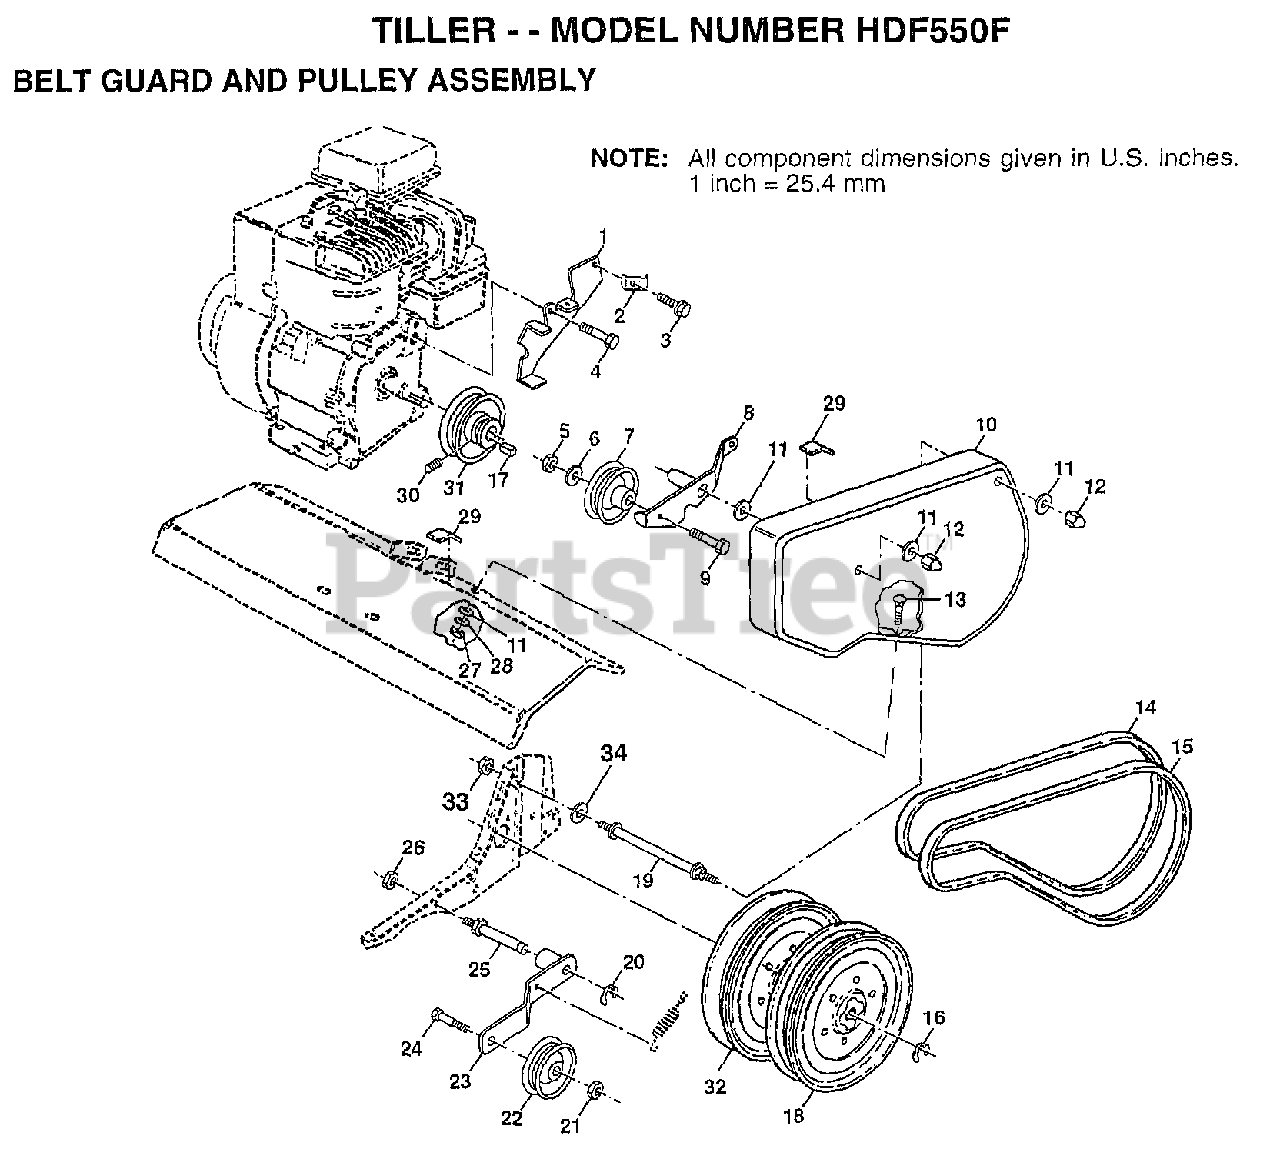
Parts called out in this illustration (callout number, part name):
1	ASM.BRKT.BELT.GRD
2	CONDIUT CLIP T
4	BOLT.HEX.HEAD
5	NUT.HEX.3/8-16UNC
6	WASHER
7	PULLEY W/SPACER
8	ARM.ASM.REV.IDLER
10	GUARD.PNT.BELT.MS-428
11	WASHER
12	NUT-CAP TI
13	BOLT T
14	BELT-V
17	KEY T
18	"SHEAVE,TRANS.""D"""
19	BOLT TI
20	KLIP RING TI
21	NUT
22	"PULLEY,IDLER"
23	"ARM, IDLER"
25	SHAFT IDLER TI
26	JAM NUT TI
28	LOCKWASHER
29	PAD IDLER TI
30	SET SCREW
31	ENGINE PULLEY TI
32	SHEAVE.TRANS
33	NUT
34	WASHER
